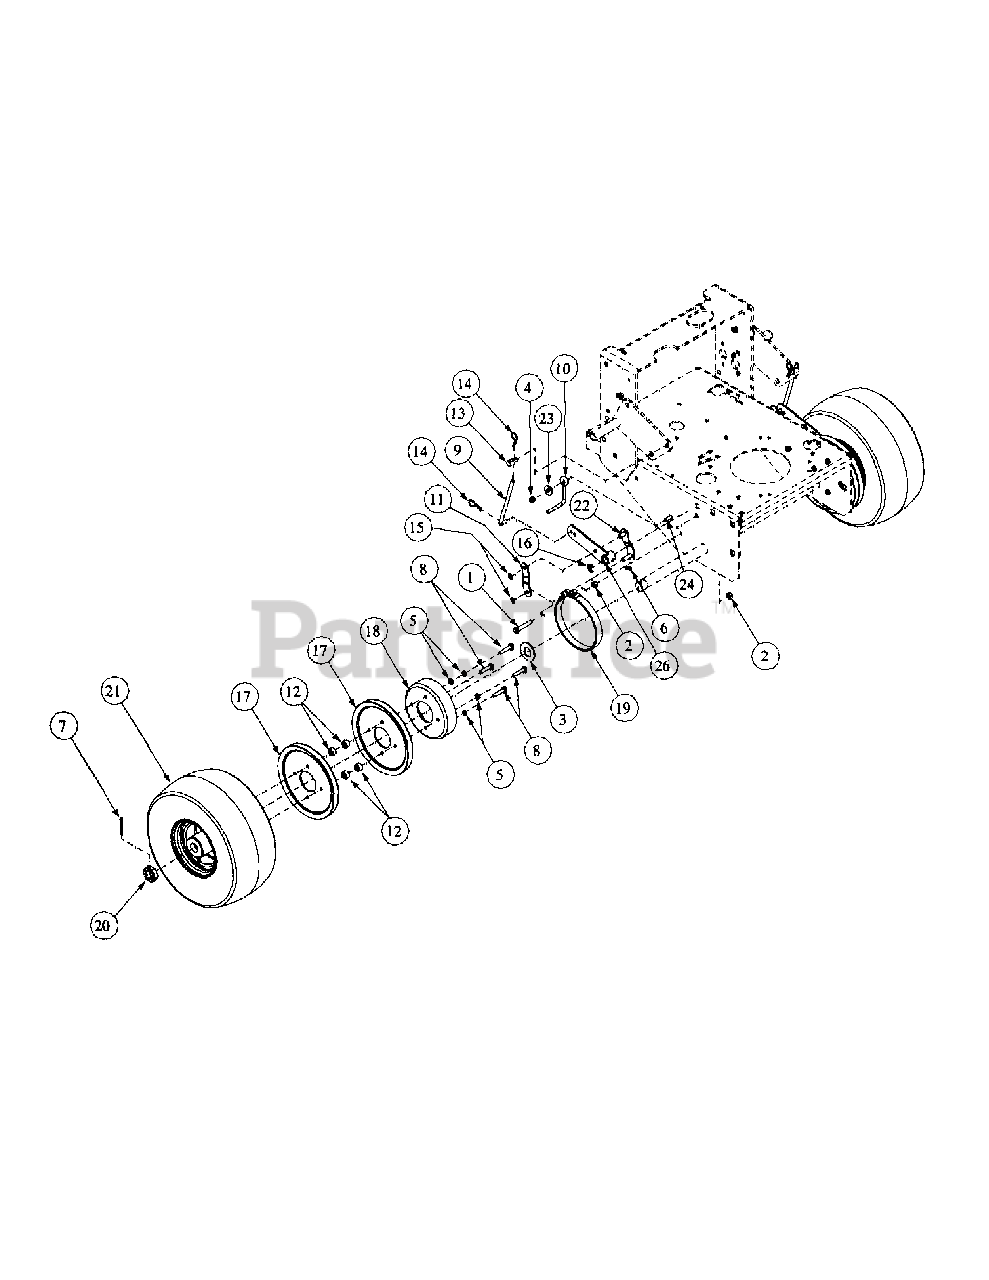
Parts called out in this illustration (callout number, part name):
1	Hex Cap Screw, 3/8-16, 2.00
2	Hex Nut, 3/8-16
3	Flat Washer, 2.000 x 1.005 x .120
4	Nut, Nylock, 5/16-18
5	Lock Washer, 5/16 Zinc
6	Grease Fitting, 1/4-28, 90°.
7	Cotter Pin, 5/32 x 1-1/2 Zinc
8	Hex Cap Screw, 5/16-18 x 1-1/2
9	Brake Rod
10	Drive Belt Guide
11	Brake, Bracket Link
12	Drive Wheel Pulley Spacer
13	Swivel Joint
14	Hair Pin, 3/8-1/2
15	Retainer, Push-on, 3/8
16	E-Ring, 5/8
17	Drive Pulley, V
18	Drum Brake
19	Band Brake
20	Hex Jam Nut, 1-14
21	Wheel Assembly, 13 x 5.00-6
22	Brake Link
23	Idler Washer
24	Carriage Bolt, 5/16-18 x 1
26	Brake Lever Weldment
